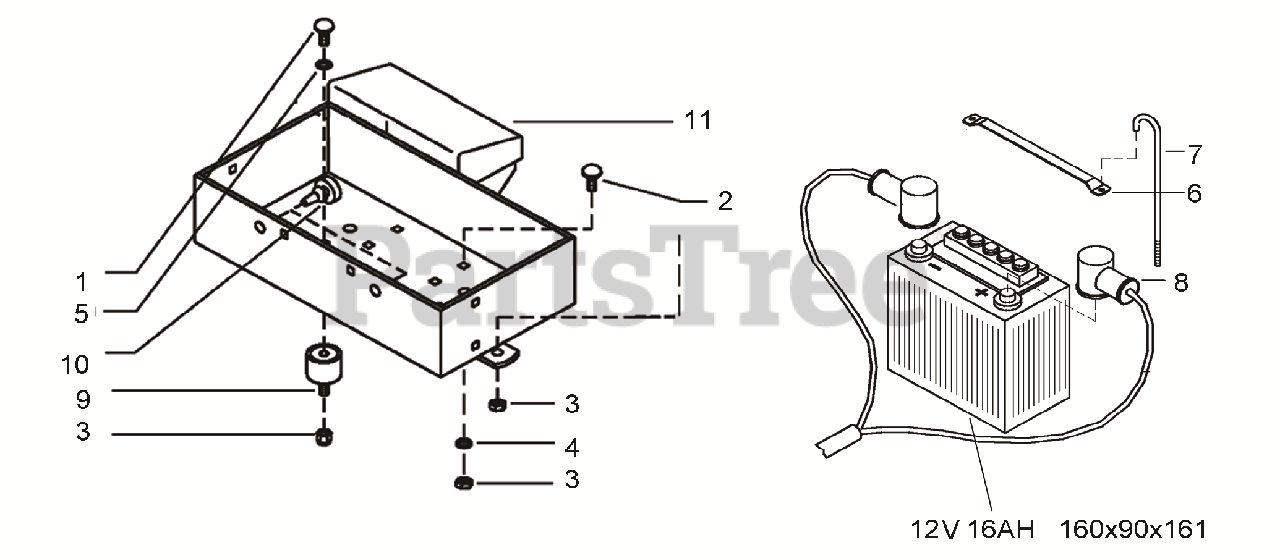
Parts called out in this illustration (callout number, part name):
1	BOLT W/SQUARE NUT M6X12
2	BOLT M6X16
3	LOCKNUT M6 STANDARD
4	WASHER FLAT M6.4X12.5
5	WASHER FLAT M9X24
6	BRACKET - BATTERY
8	CABLE - ELECTRIC STARTER
9	RUBBER BUFFER - VIBRATION
10	RUBBER STOPPER
11	BOX - BATTERY
